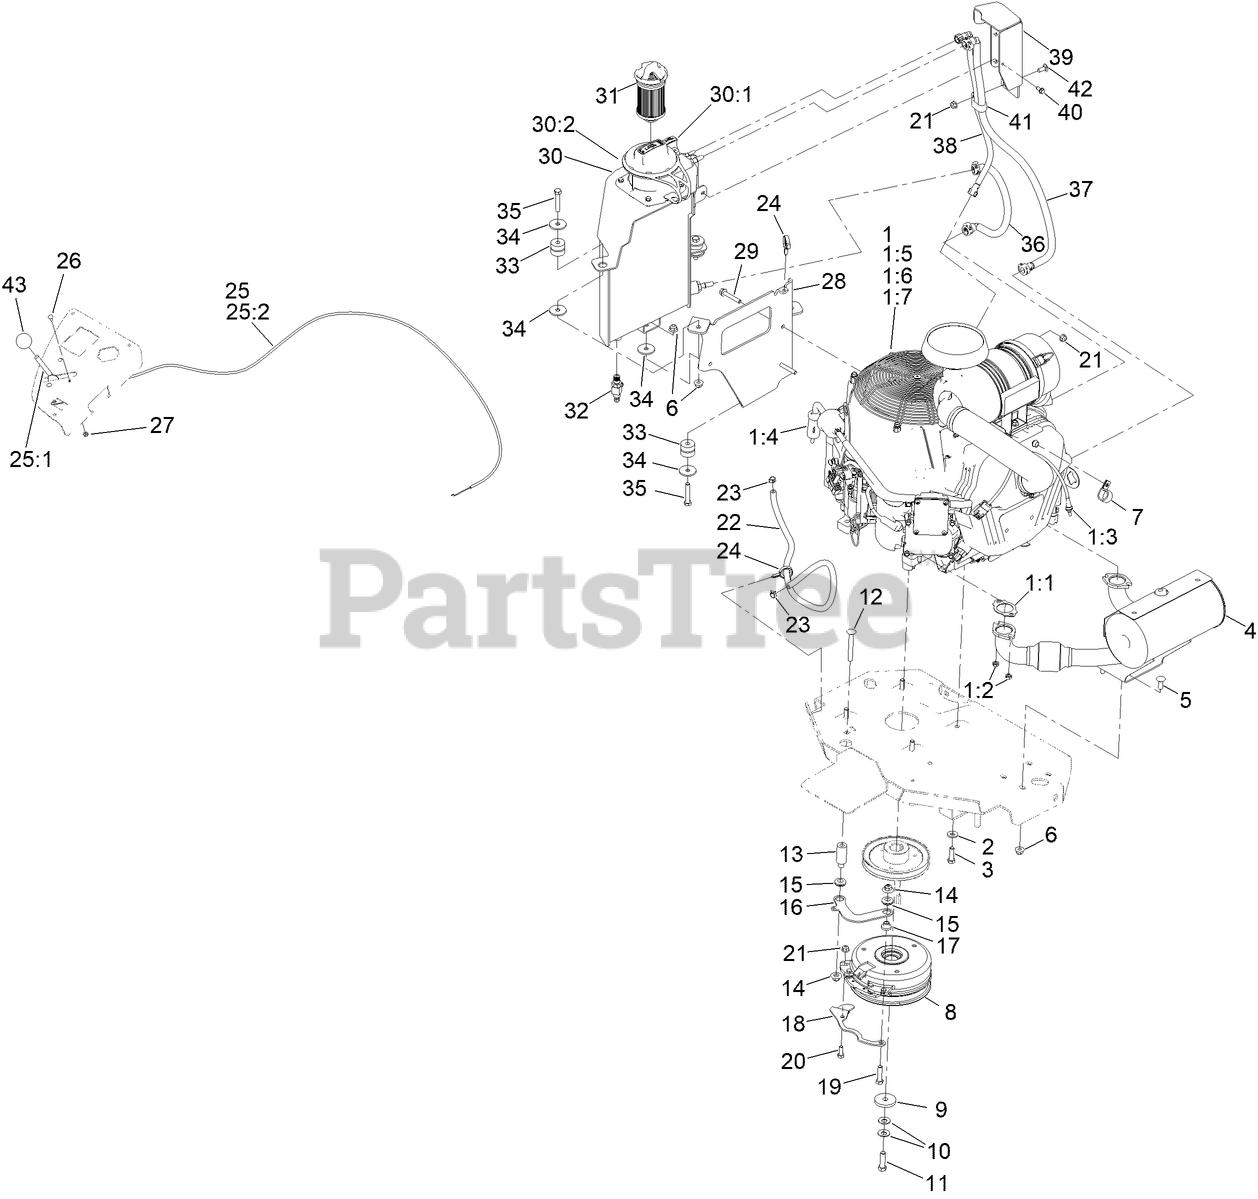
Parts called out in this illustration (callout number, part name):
1	ENGINE-VANGUARD
1:1	GASKET-EXHAUST
1:2	NUT-HEX
1:3	SENSOR-O2
1:4	FILTER-FUEL
2	WASHER-BELLEVILLE
3	SCREW-HH
4	MUFFLER
5	SCREW-CARR
6	NUT-HF, NI
7	R-CLAMP
8	CLUTCH KIT
9	WASHER-CLUTCH
10	WASHER-SPRING
11	SCREW-HH, W/LOCTITE
12	SCREW-CARR
13	SPACER
14	NUT-FLANGE, NI
15	GROMMET-RUBBER
16	LINK-ANCHOR, CLUTCH
17	SPACER
18	BELT-GUIDE
19	SCREW-HH
20	SCREW-HH
21	NUT-HF, NI
22	HOSE-FUEL
23	CLAMP-HOSE
24	CLAMP-HOSE
25	THROTTLE CONTROL ASM
25:1	LEVER-THROTTLE
26	BOLT-CARR
27	NUT-LOCK, NI
28	MOUNT-TANK, OIL
29	SCREW-HHF
30	RESERVOIR-OIL
30:1	OIL DIPSTICK ASM
30:2	OIL TANK CAP ASM
31	FILTER-OIL
32	VALVE-OIL DRAIN
33	ISOLATOR-TANK
34	WASHER
35	SCREW-HH
36	HOSE-SUPPLY
37	HOSE-SCAVENGE
38	HOSE-VENT
39	GUARD-HOSE
40	SCREW-HWH
42	SCREW-CARR
43	KNOB-BALL
